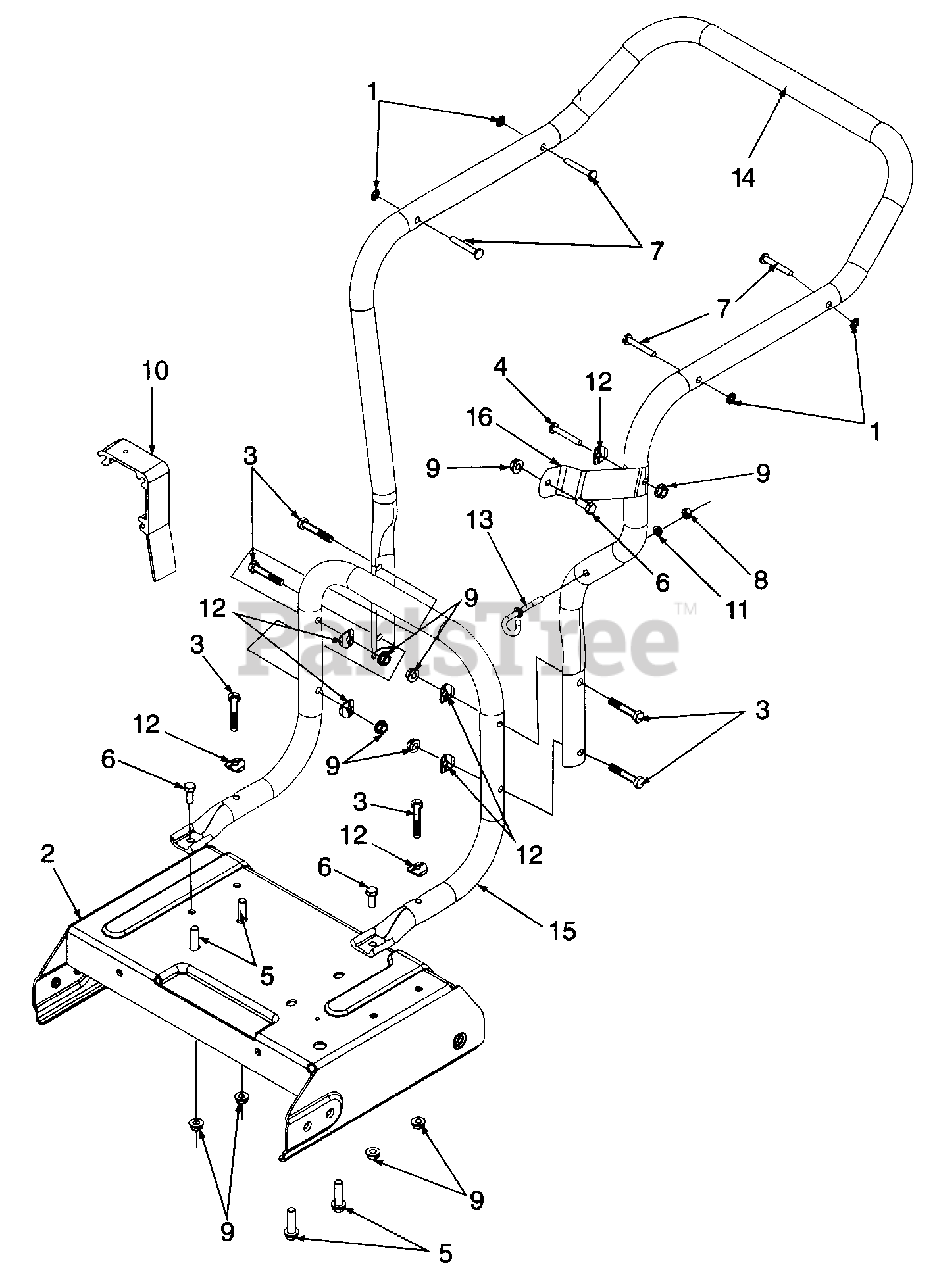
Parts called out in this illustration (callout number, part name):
1	Nut, Push
4	Screw, Hex Cap, 5/16-8 x 1.50
5	Screw, Hex Wash. Hd. Tapp, 3/8-16 x 1.25
6	Screw, Hex Cap, 5/16-18 x .75
7	Pin, Stud, .250 x 1.75
8	Nut, Hex, 1/4-28
9	Nut, Hex Flange Lock, 5/16-18
10	Adapter, Mounting
11	Washer, Lock, 1/4
12	Washer, Saddle, .32 ID x .93 OD
13	Bolt, Eye
